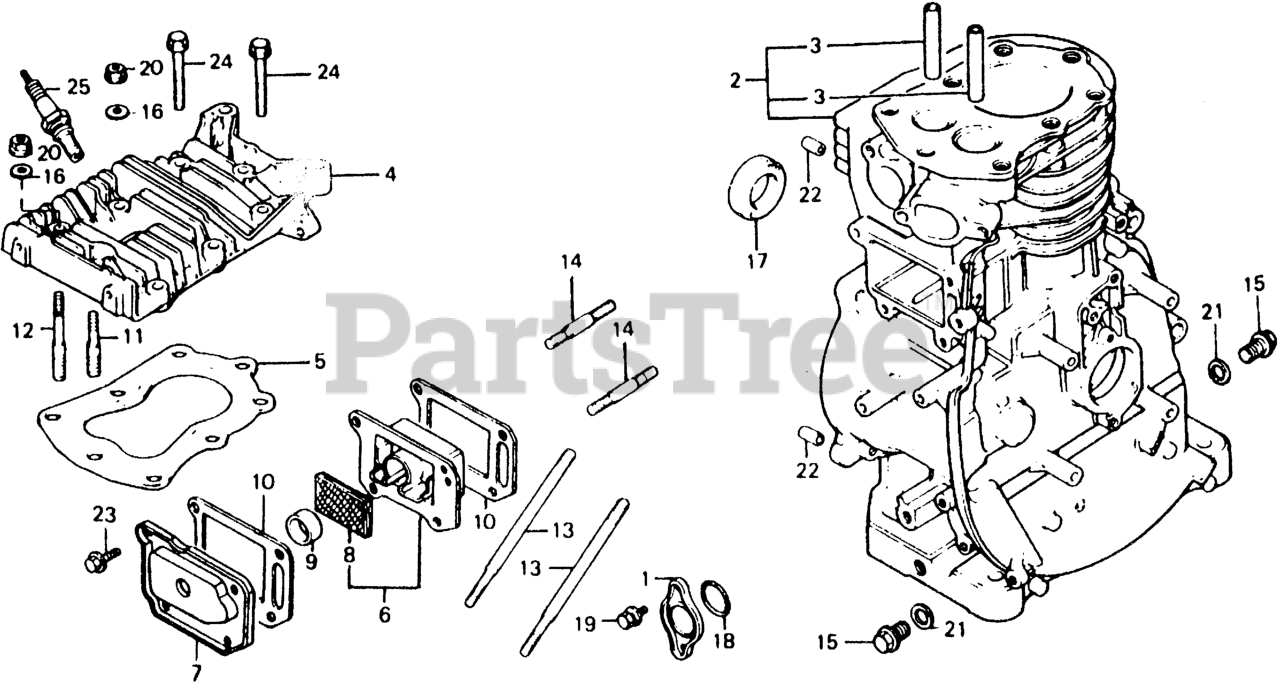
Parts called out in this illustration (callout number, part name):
1	COVER, OIL PAN
2	CYLINDER
3	GUIDE, VALVE
4	CYLINDER HEAD
5	GASKET, CYLINDER HEAD
6	CASE, BREATHER
7	COVER, TAPPET
8	FILTER, BREATHER
9	SEAL, BREATHER
10	GASKET, TAPPET COVER Use up to Engine SN 1136497.
11	BOLT, STUD (M8XM10X63)
12	BOLT, STUD (M8XM10X81)
13	BOLT, STUD (8X110)
14	BOLT, STUD (8X35)
15	BOLT, DRAIN PLUG
16	WASHER (8MM)
17	OIL SEAL (25X41X6)
18	O-RING (27X2.0)
19	BOLT-WASHER (6X12)
20	NUT-WASHER (8MM)
21	WASHER, DRAIN PLUG (12MM)
22	PIN A, DOWEL (8X14)
23	BOLT, FLANGE (6X12) Use up to Engine SN 1543277.
24	BOLT, FLANGE (8X50) (NOT AVAILABLE)
25	SPARK PLUG (BR-4HS) (NGK)
